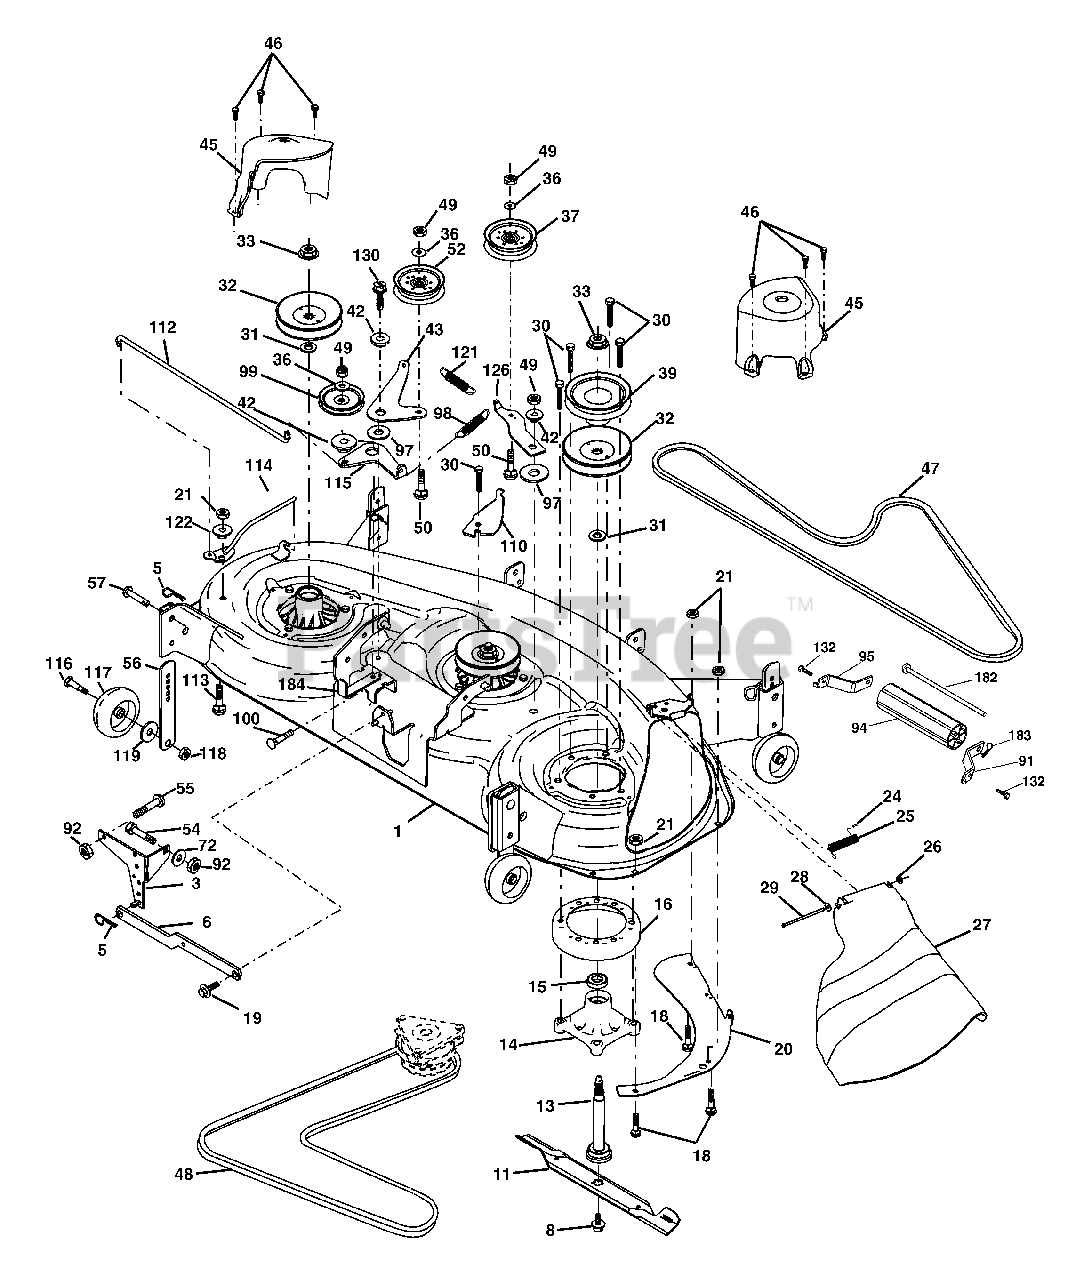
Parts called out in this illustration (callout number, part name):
1	Deck Weldment Mower 48
3	Bracket Asm., Sway Bar
5	Retainer Spring
6	Arm, Suspension, Rear Sway Bar Deck
8	Bolt 7/16 Asm. Blade
11	Blade, 48" Mulching
11	Blade, 48" Hi-Lift
13	Shaft Asm. w/Lower Bearing
14	Mandrel Asm. Housing
15	Bearing, Ball, Mandrel
16	Stripper Mandrel Deck
17	Bolt RDHD Sq Neck 3/8-16 x 1.25
18	Bolt, Carriage 5/16-18 x 5/8
19	Bolt, Hex Hd, Shoulder 5/16-18
20	Baffle, Vortex Mower
21	Nut, Crownlock 5/16-18 Unc
24	Cap, Sleeve
25	Spring, Torsion
26	Nut, Push
27	Deflector Shield
28	Washer 11/32 x 5/8 x 16 Ga.
29	Rod, Hinge
30	Screw, Thdroll Washer Head
31	Washer, Spacer Mower Vented
32	Pulley, Mandrel
33	Nut, Flg. Top Lock Cntr. 9/16
36	Washer 13/32 x 13/16 x 16 Ga.
37	Pulley, Idler, Flat
39	Pulley, Idler, Driven
42	Spacer, Retainer
43	Arm, Idler Secondary
45	Cover, Mandrel Deck
46	Screw, Thdroll. 1/4-20 x 5/8
47	V-Belt, Mower, Secondary
48	V-Belt, Mower, Primary
49	Nut, Crownlock 3/8-16 Unc
50	Bolt, Carr. 3/8-16 x 1-1/2 Gr. 5
52	Pulley Idler Flat
54	Bolt Fin Hex 3/8-16 x 1
55	Bolt Carriage Sqnk. 3/8-16 x 1
56	Bar Pnt Adj.
57	Pin Head Rivet
72	Washer 13/32 x 13/16 x 12 Ga.
91	Bracket, Asm Noseroller, RH
92	Nut Lock Hex 3/8-16
94	Noseroller
95	Bracket, Asm Noseroller LH
97	Washer Hardened
98	Spring Primary Drive
99	Pulley Idler "V"
100	Bolt RDHD Sqnk 3/8-16 Unc x 2
110	Arm Spring Secondary
112	Link Tension Relief Lever
113	Bolt 5/16-18 x 3/4
114	Tension Asm. Relief Lever
115	Arm Spring Tension Relief
116	Bolt, Shoulder
117	Gauge Wheel
118	Nut, Centerlock 3/8-16 Unc
119	Washer 3/8 x 7/8 x 14 Ga.
121	Spring Secondary Drive
122	Bushing Pivot Tension Relief
126	Arm, Idler, Primary Deck
130	Screw 3/8-16 x 1.0
132	Screw 3/8-16 x .75
182	Rod Roller Nose
183	Retainer Spring
184	Keeper Belt Idler
